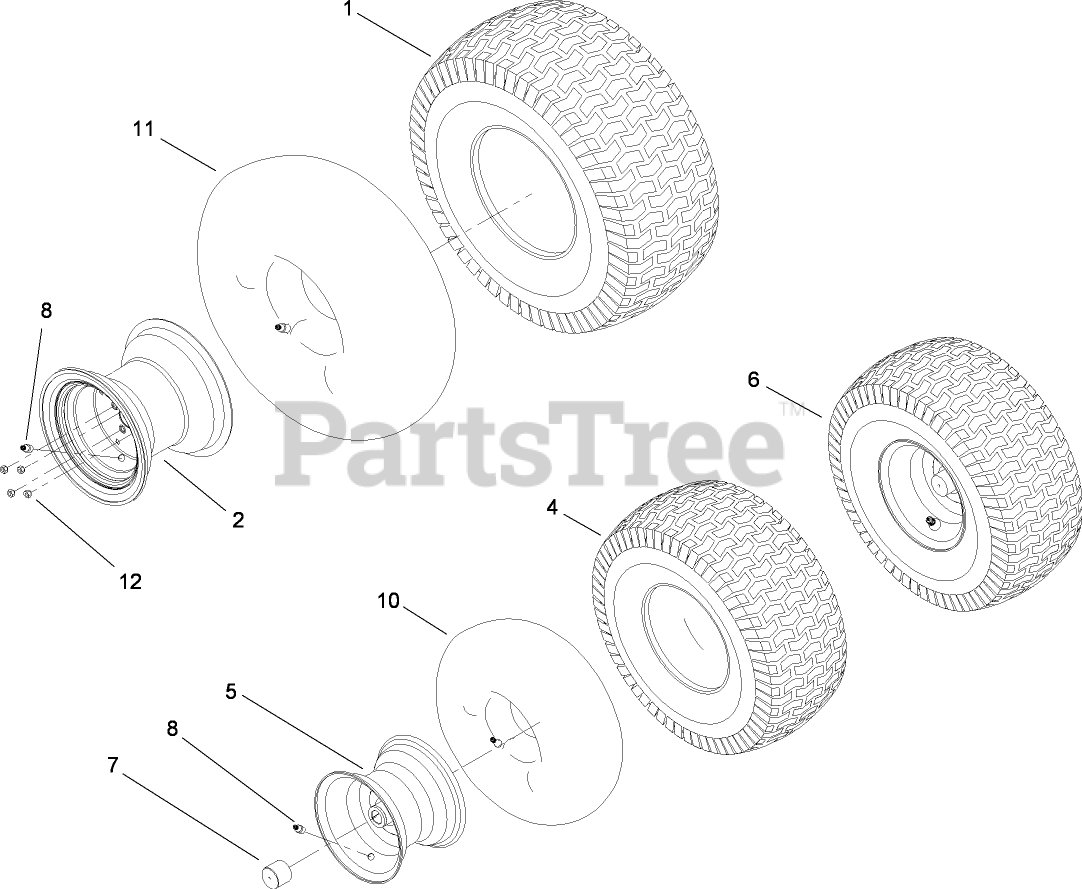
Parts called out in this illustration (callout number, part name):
1	TIRE 22X9.50X12 SQ SHOULDER
2	RIM ASM
4	TIRE-TURF
5	RIM-WHEEL, FRONT
6	WHEEL ASM
7	CAP-HUB
8	VALVE-AIR, TUBELESS
10	TUBE-INNER
11	TUBE-INNER
12	NUT-LUG
